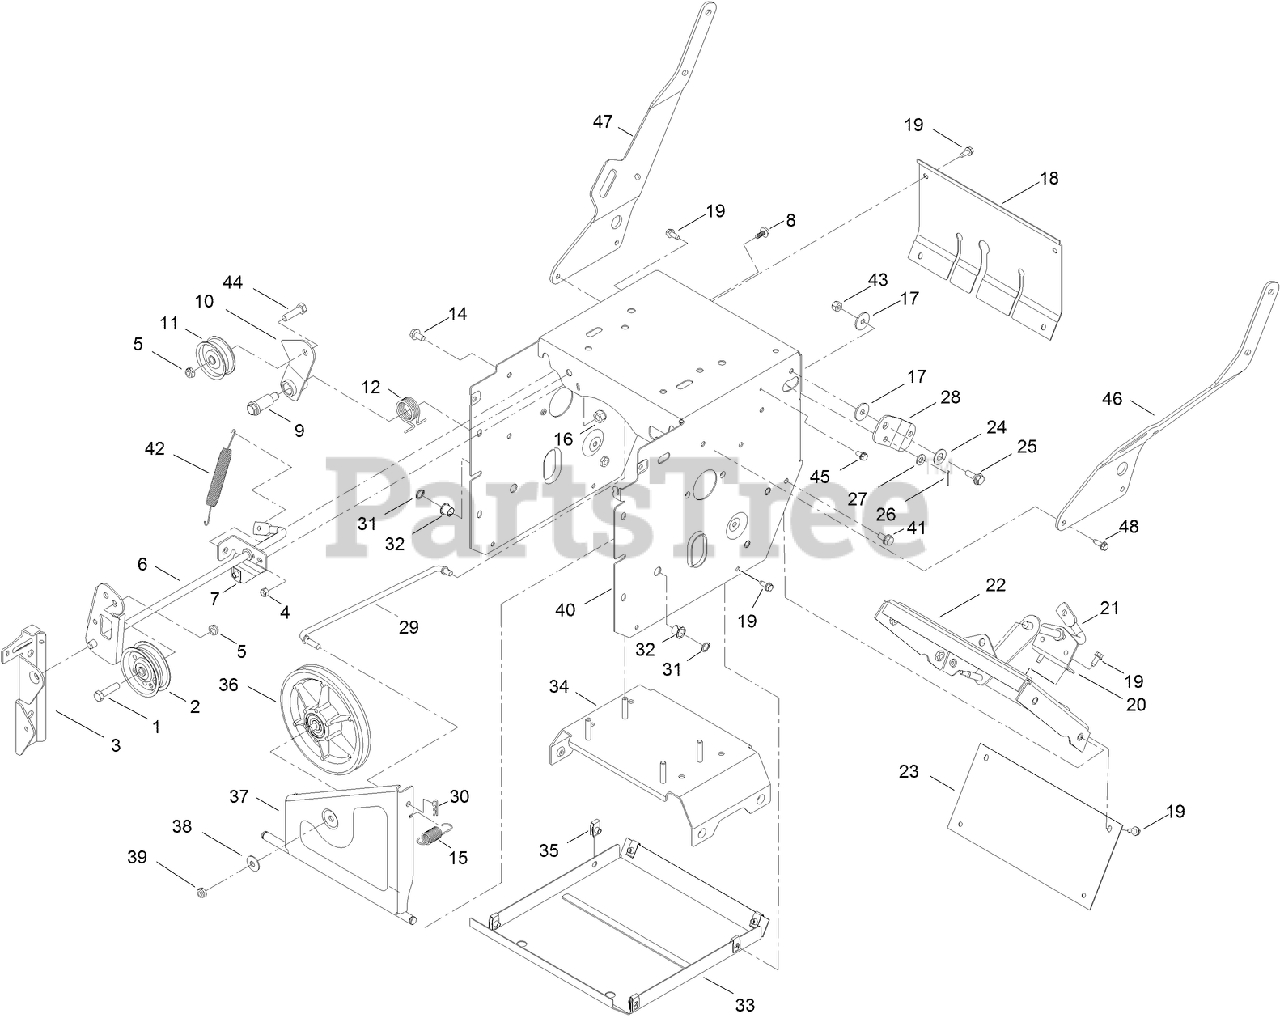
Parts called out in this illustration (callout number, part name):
1	SCREW-HH
2	PULLEY-IDLER
3	BRACKET-IDLER, IMPELLER
4	NUT-LOCK, NI
5	NUT-LOCK, NI
6	IMPELLER CLUTCH ASM
7	BRACKET-CLUTCH, IMPELLER
8	SCREW-HHF
9	BOLT-SHOULDER
10	ARM-IDLER, TRACTION
11	PULLEY-IDLER
12	SPRING-TORSION
14	SCREW-HHF
15	SPRING-EXTENSION
16	NUT-LOCK, NI
17	WASHER-PIVOT
18	COVER-UPPER
19	SCREW-HWH
20	BRACKET-ROD, SHIFT
21	LEVER-CONTROL, TRACTION
22	SHIFT PLATE ASM
23	COVER-LOWER
24	WASHER
25	SCREW-SHOULDER
26	PIN-COTTER
27	WASHER-PLAIN
28	BELLCRANK-DRIVE
29	LINK-CONTROL, SPEED
30	PIN-COTTER
31	RING-RETAINING
32	BUSHING-NYLINER
33	PAN-BOTTOM
34	BRACE-FRAME
36	PULLEY-TRACTION
37	BRACKET-WHEEL, FRICTION
38	WASHER-BELLEVILLE
39	NUT-HEX
40	FRAME-TRACTION
41	SCREW-HWHTF
42	SPRING-EXTENSION
43	NUT-LOCK, NI
44	SCREW-HH
45	SCREW-HWH
46	BRACE-HANDLE, LH
47	BRACE-HANDLE, RH
48	SCREW-HWH, THREAD ROLL
